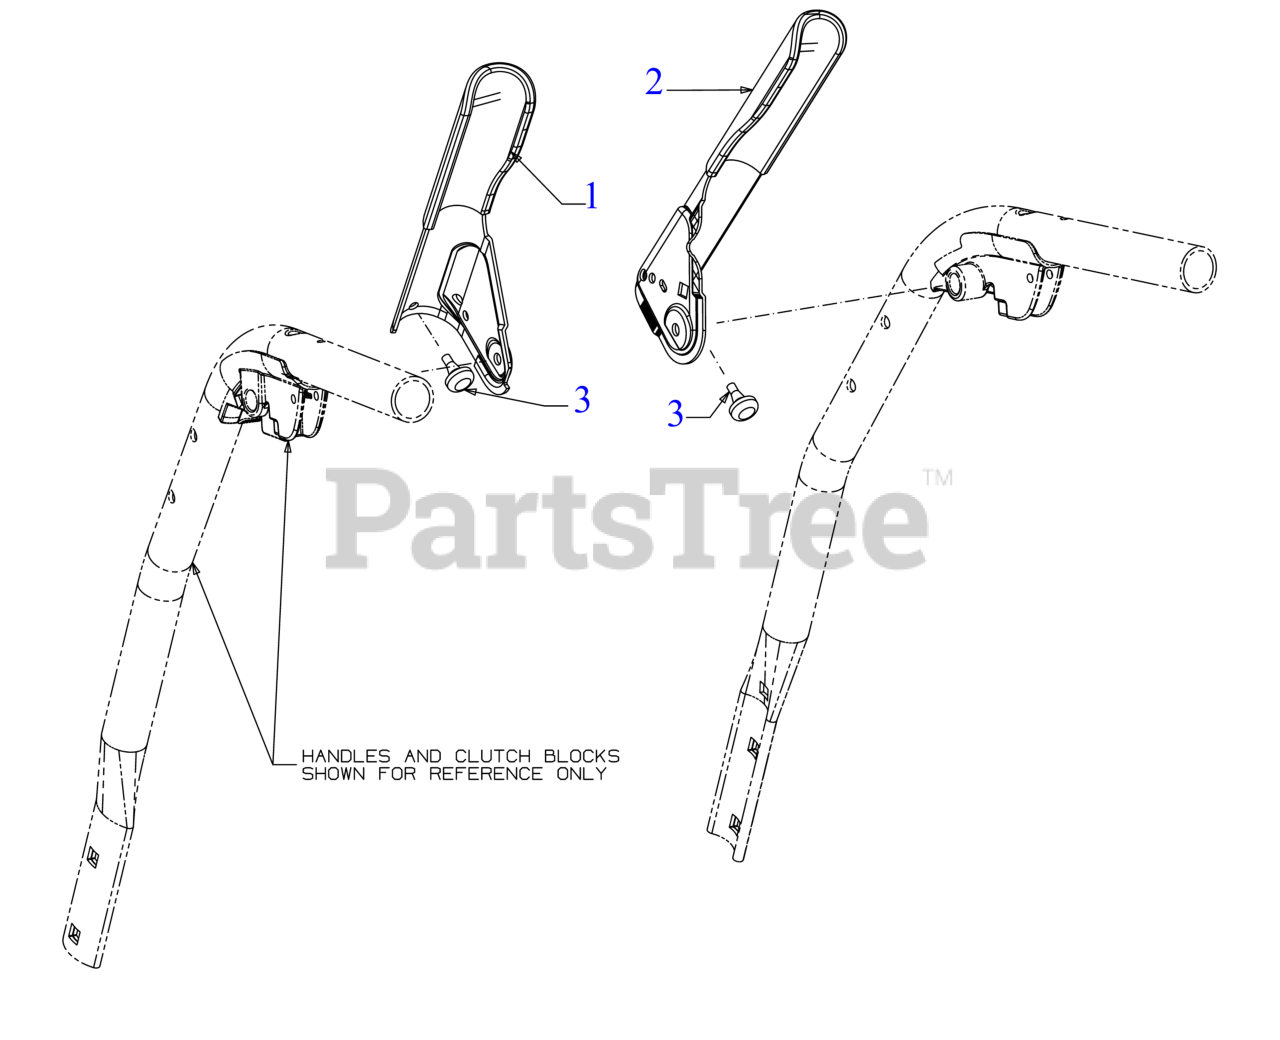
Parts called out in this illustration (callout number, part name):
1	HANDLE ASSEMBLY (LH)
2	HANDLE ASSEMBLY (RH)
3	RUBBER BUMPER
